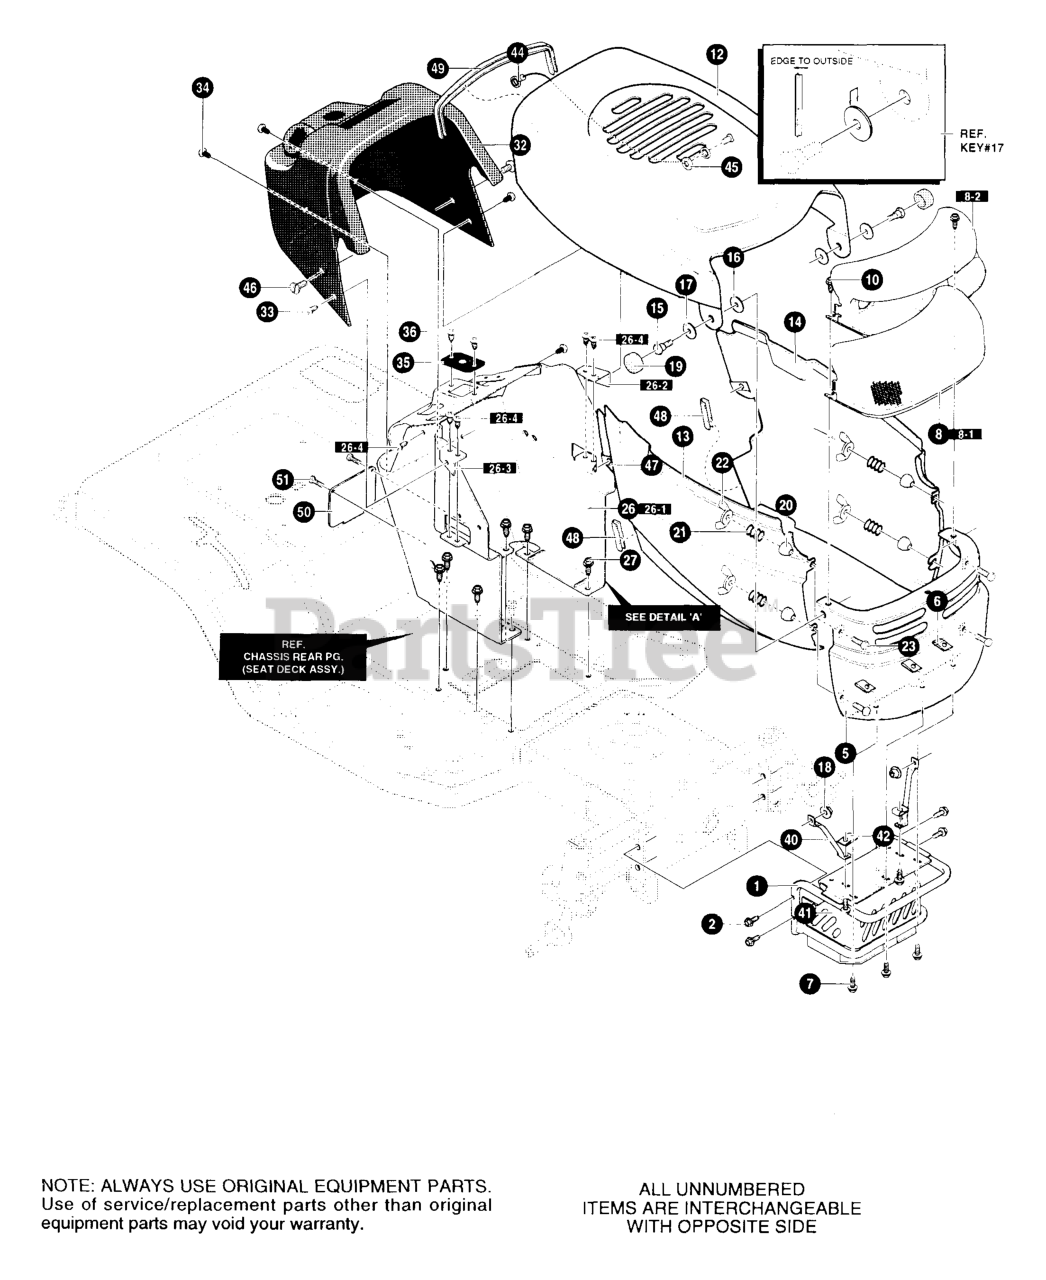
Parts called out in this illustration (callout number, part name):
1	WELD. ASM COMMON BUMP/GRIL MNT
2	SCREW 5/16-18X1.50 HHWATAP
6	NUT, "J" TINNERMAN #C702-1420Z
7	SCREW 1/4-20X.63 HHWATAPSERBZ
8	ASM. LENS & REFLECTOR
8-2	REFLECTOR
10	SCREW, 1/4-14X.50 PANCR
12	WELD ASSEMBLY HOOD
13	PANEL, SIDE RH
14	PANEL, SIDE LH
15	BOLT, .497X.215HHSH 3/8-16
16	WASHER, PLASTIC
17	PIVOT BASE
18	NUT, 3/8-16 HWDFLLK MACK 15X84
19	CAP, PIVOT
20	QUICK RELEASE-CAM
21	SPRING, COMP.500DX.5LG
22	NUT, WING 1/4-20 NYLON
23	SCREW, 1/4-20X1.25
26	CONSOLE ASSY
26-1	CONSOLE DASH MAN PTO
26-2	BRACKET, HOME DEPOT LH
26-3	BRACKET, HOME DEPOT RH
26-4	SCREW, 10-24X.500 SEGI
27	SCREW 5/16-18HHWATAP
33	SCREW 10-24X.500TRSEGI
34	SCREW 10-24X.500TRSEGI
35	BRACKET, STEERING
36	SCREW, 1/4-14X.50 PANCR
40	STRUT, GRILLE
41	SCREW 1/4-20X.63 HHWATAP
42	SPEED NUT
44	LANYARD, HOOD
45	PUSHNUT
46	SCREW, 1/4-20X.63 PHPNHD
47	NUT, "J" TINNERMAN #C702-14202
48	TRIM, PIECE PLASTIC
49	TRIM, PIECE PLASTIC
50	ACCESS PANEL W/O SLOT
51	SCREW 10-24X.500TRSEGI
